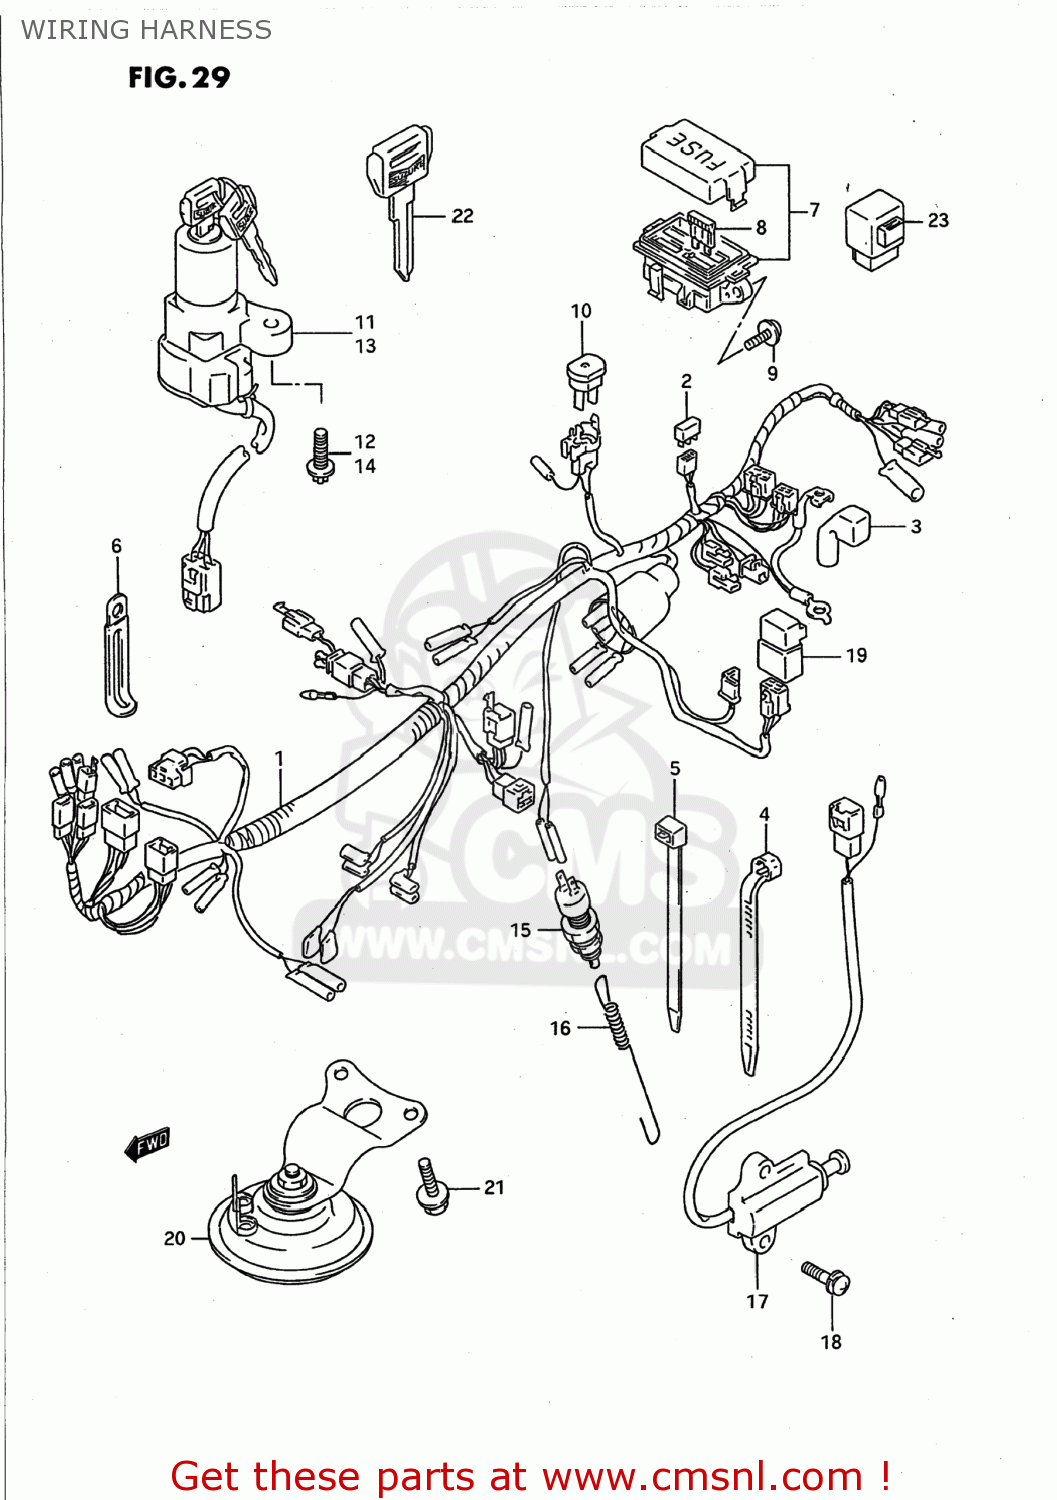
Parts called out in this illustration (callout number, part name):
1	HARNESS,WIRING
2	DIODE(STANLEY DE8804)
3	CAP,BATTERY PLUS
4	CLAMP(L:95)
5	CLAMP(L:95)
6	CLAMP(L:120 T:1.0)
7	BOX ASSY,FUSE
8	FUSE(10A)
9	SCREW
10	BREAKER ASSY,CIRCUT
11	LOCK ASSEMBLY,STEERING
12	SCREW(6X18)
13	LOCK ASSEMBLY,STEERING
14	SCREW(6X18)
15	SWITCH ASSY,STOP LAMP
16	SPRING
17	SWITCH ASSY,SIDE STAND
18	BOLT
19	RELAY ASSY
20	HORN ASSY
21	BOLT
22	KEY,BLANK
23	CONTROLLER ASSY,FAN MOTOR
